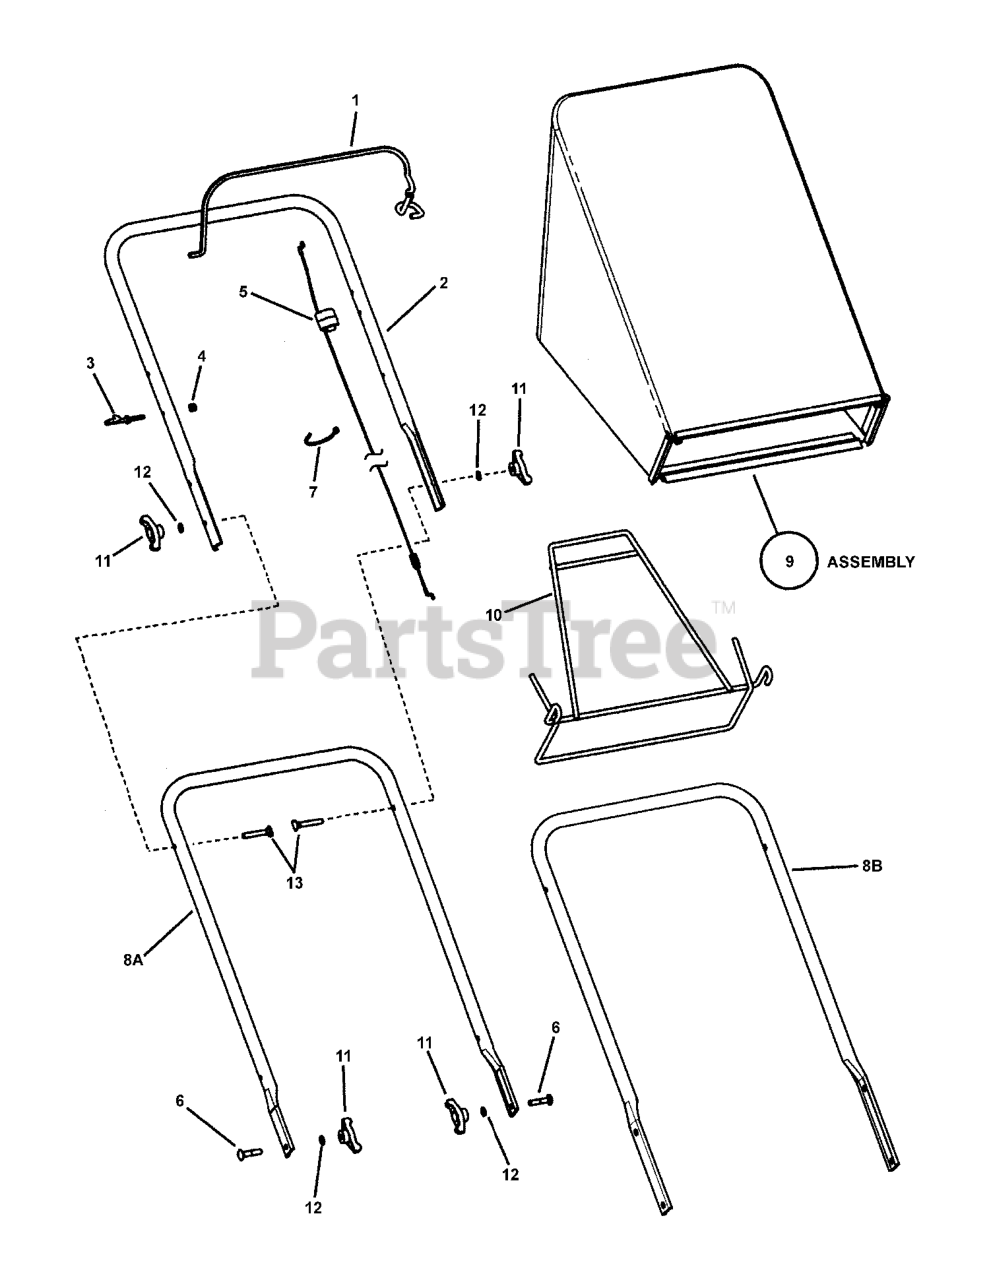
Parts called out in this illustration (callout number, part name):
1	BAIL, OPC Push
2	UPPER HANDLE, Propelled
3	GUIDE, Rope (1/4-20 thread)
4	NUT, 1/4-20 Nyloc
5	CABLE, Bail, (45.00" overall length)
5	CABLE, Bail, 22" WBM, (41.50" overall length)
5	CABLE, Zone Control (48.60" overall length)
6	BOLT, 5/16-18 x 1-1/2" Square Neck Carriage GR 1
6	BOLT, 5/16-18 x 1-1/2" Short Square Neck Carriage GR 5
7	WIRE TIE, 11 Inch Standard Black Nylon
8A	HANDLE, Lower
8B	HANDLE, Lower
9	ASSY, Grass Bag, Cloth (incl. next item below)
10	WELDMENT, Frame, Grass Bag
11	KNOB, 5/16-18 Wing
12	WASHER, 5/16" Internal Tooth Lock
13	BOLT, 5/16-18 x 2" Curved Head Square Neck GR 2
